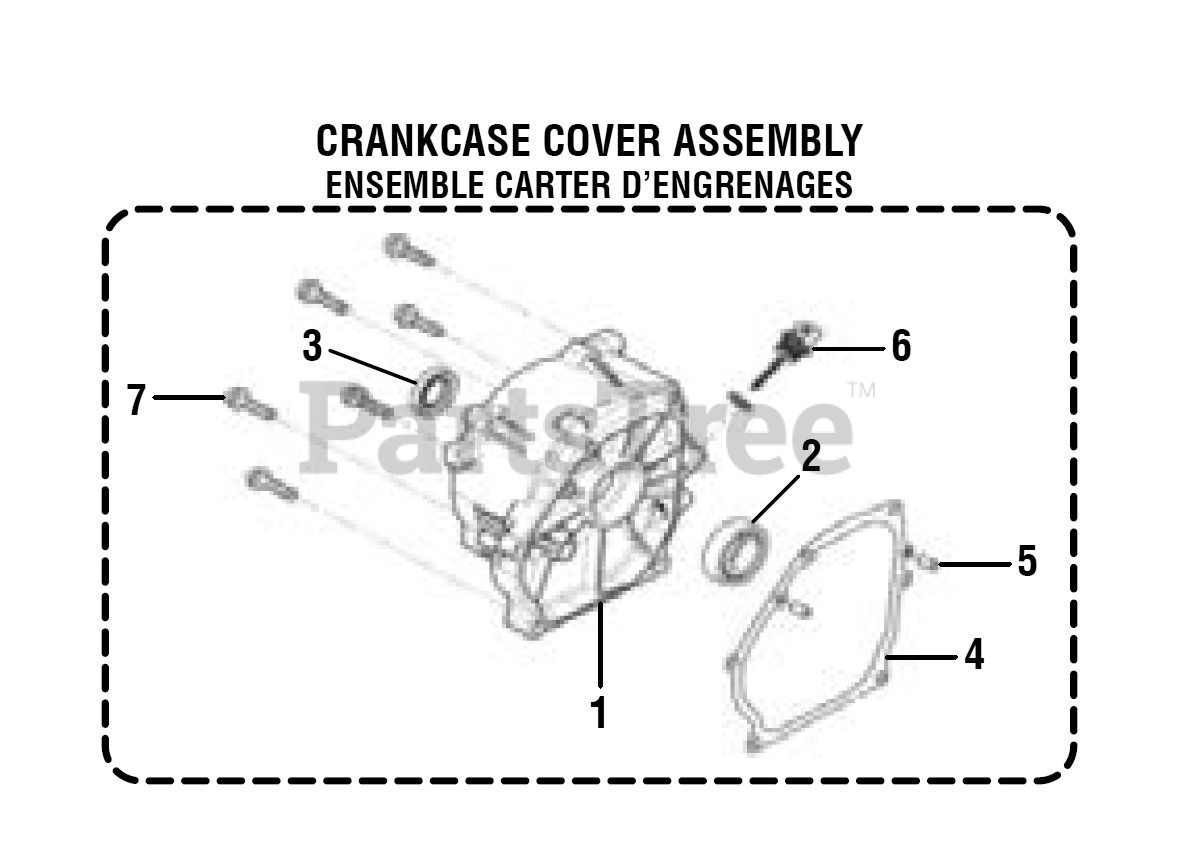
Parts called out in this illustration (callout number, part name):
1	Crankcase Cover
2	Ball Bearing
3	Oil Seal
4	Crankcase Gasket
6	Oil Dipstick Assembly
